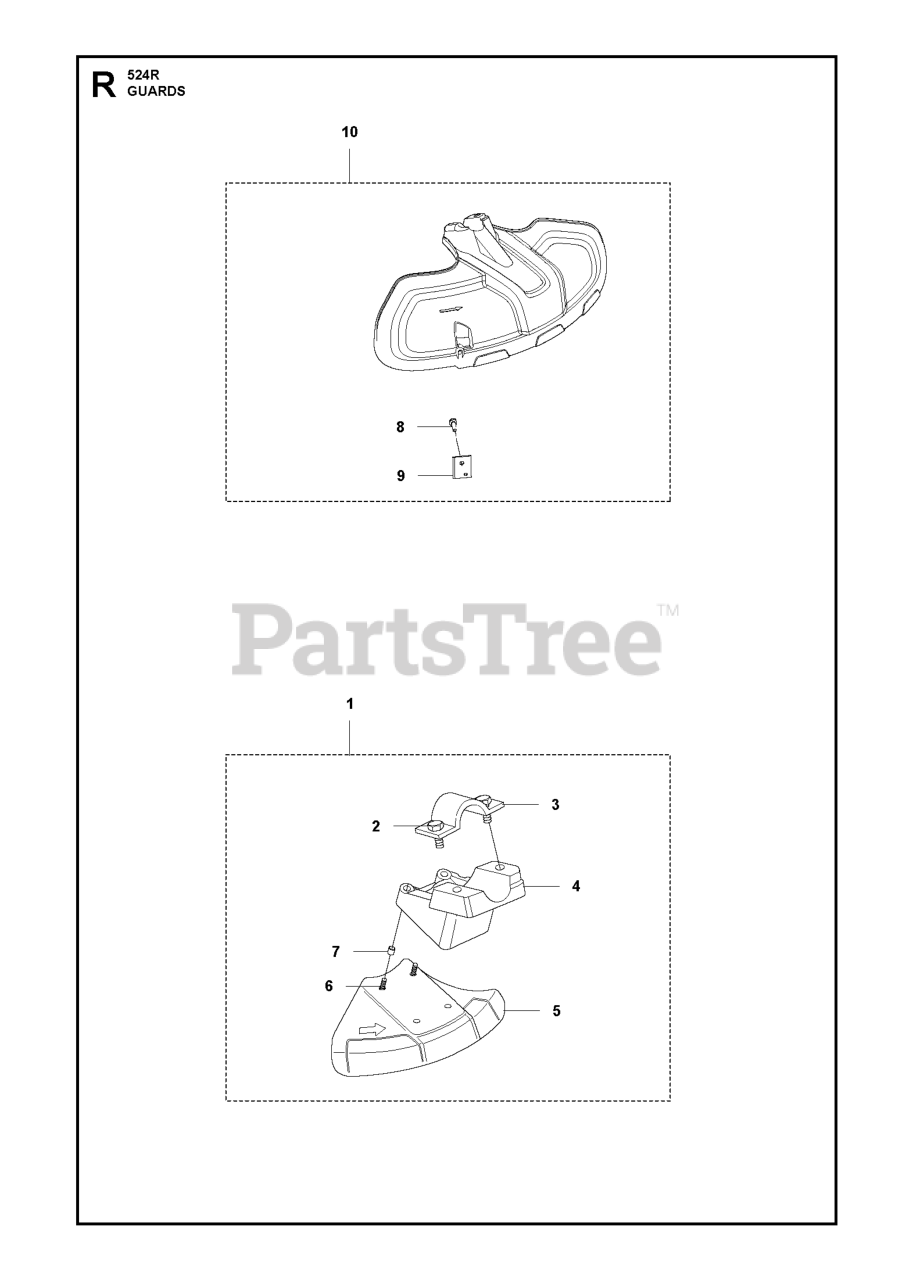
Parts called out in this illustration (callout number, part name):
1	ACCESSORY BAG
2	SCREW IHSCFMO
3	CLAMP ASSY
5	BLADE GUARD
7	LOCKING NUT
8	SCREW ITXSCFT PW4.8X16 T27 CH
10	COMBINATION GUARD
